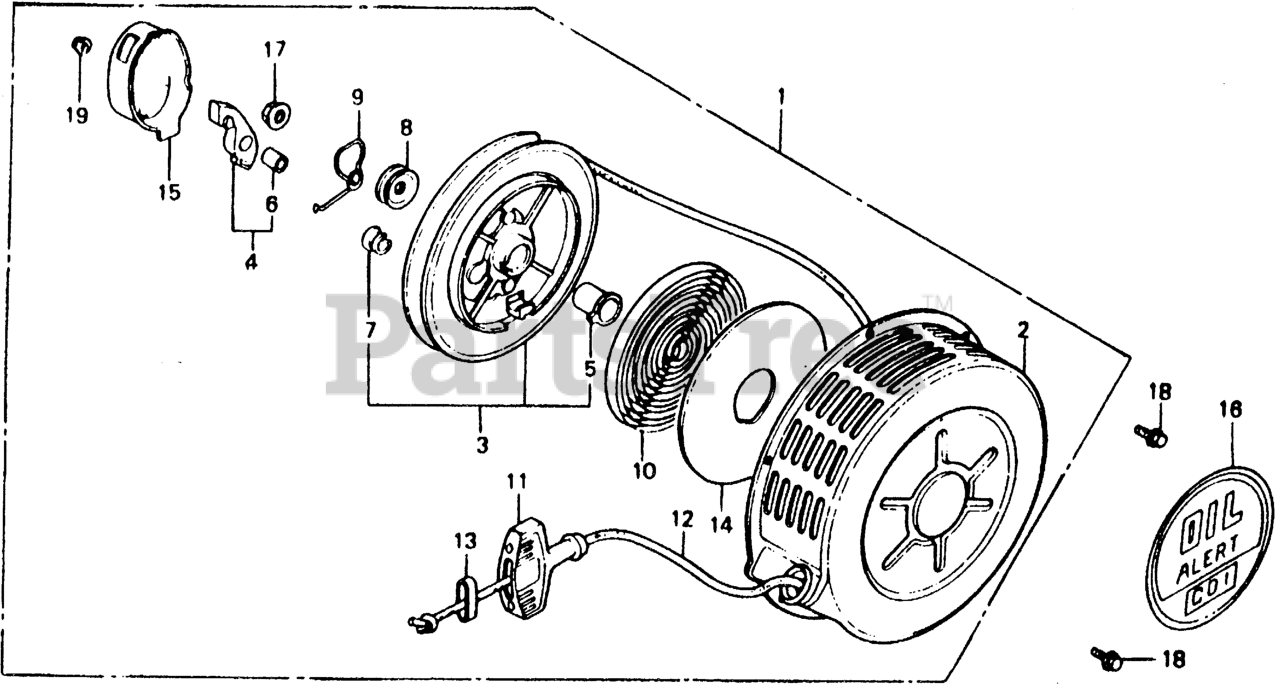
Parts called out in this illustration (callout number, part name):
1	STARTER ASSY., RECOIL *R8* (BRIGHT RED)
2	CASE, STARTER *R8* Use up to Engine SN 1045974.
3	REEL, STARTER
4	RATCHET
5	BOSS, REEL
6	BUSH, RATCHET
7	BUSH, REEL STARTER
8	PLATE, FRICTION
9	SPRING, FRICTION
10	SPRING, RETURN
11	GRIP, STARTER
12	ROPE, RECOIL STARTER (#5X59") (NA USE ALT:08550-ZG921-11)
13	SUPPORT, GRIP
15	COVER, REEL STARTER
16	LABEL, OIL ALERT
17	NUT, SELF-LOCK (8MM)
18	BOLT-WASHER (6X10)
19	NUT, FLANGE (5MM)
